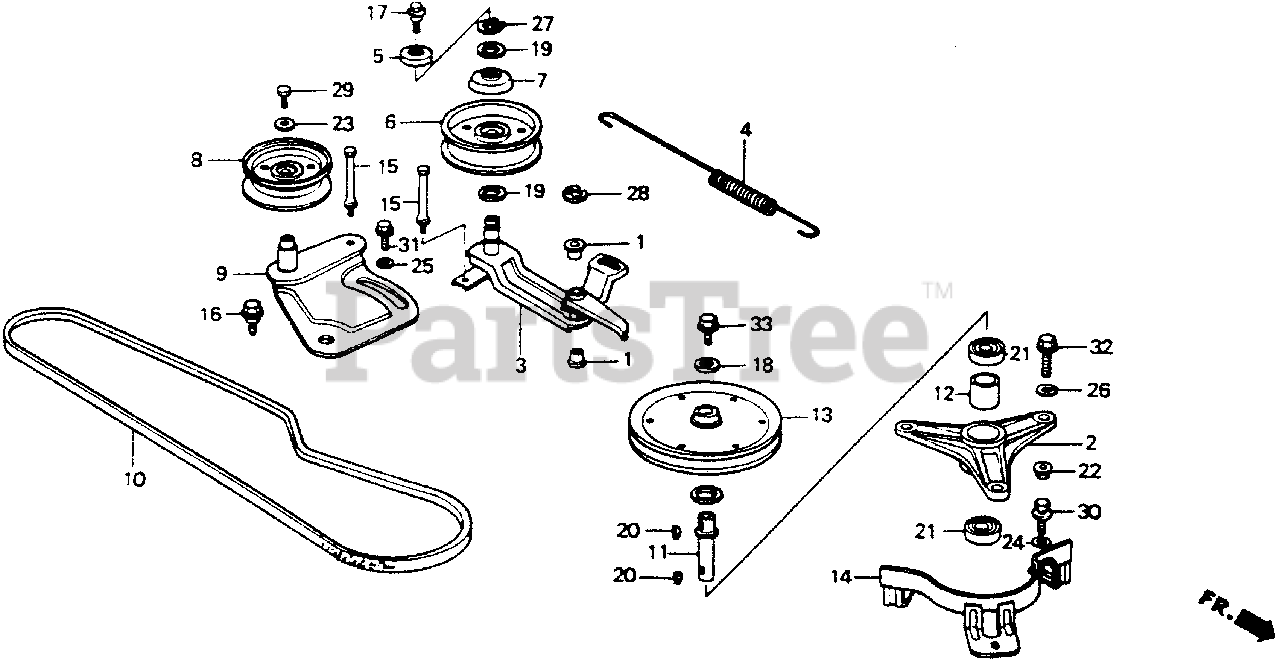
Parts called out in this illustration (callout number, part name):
1	BUSH (15X19X22)
2	HOUSING, BEARING (NOT AVAILABLE)
3	ARM, TENSION (DECK) (NOT AVAILABLE)
4	SPRING, TENSIONER ARM
5	GRIP, TENSION ARM (NOT AVAILABLE)
6	ROLLER, TENSIONER
7	DUST COVER, TENSION PULLEY (NOT AVAILABLE)
8	PULLEY, TENSIONER
9	ARM, BELT ADJUSTING
10	V-BELT, BLADE (SB-70)
11	SHAFT, BLADE (NOT AVAILABLE)
12	COLLAR, BLADE SHAFT (NOT AVAILABLE)
13	PULLEY, CUTTER DECK (NOT AVAILABLE)
14	COVER, DECK PULLEY (NOT AVAILABLE)
15	BOLT, BELT STOPPER
16	BOLT, ADJUSTING ARM
17	BOLT, FLANGE (6MM)
18	WASHER (12.2X33X3.2)
19	WASHER (17.3X25)
20	KEY, SPECIAL WOODRUFF (16X15)
21	BEARING, RADIAL BALL (62/22) (2RS)
22	NUT, FLANGE (10MM)
23	WASHER, PLAIN (6MM)
24	WASHER, PLAIN (6MM)
25	WASHER, PLAIN (8MM)
26	WASHER, SPRING (10MM)
27	CIRCLIP (OUTER) (17MM)
28	E-RING (12MM)
29	BOLT, FLANGE (6X12)
30	BOLT, FLANGE (6X16)
31	BOLT, FLANGE (8X16)
32	BOLT, FLANGE (10X35)
33	BOLT, FLANGE (12X25)
